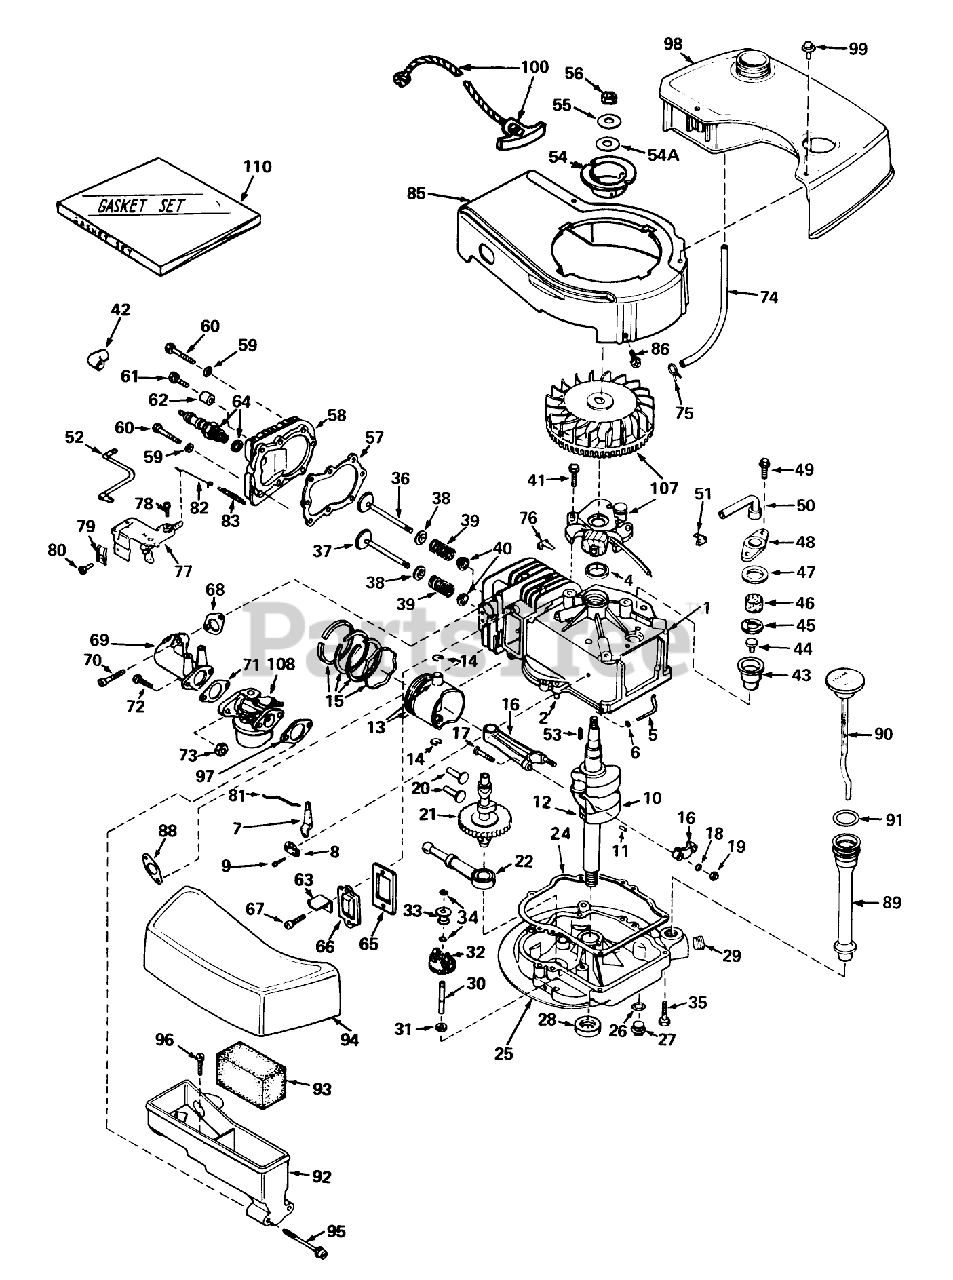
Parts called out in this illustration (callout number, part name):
1	Cylinder Assy. (Incl. Ref. #2, 4 105)
2	Pin-Dowel
4	OIL SEAL
5	Rod, Governor (Incl. No. 36)
6	Washer-Flat
7	Governor Lever
8	Clamp-Lever, Governor
9	Screw
10	Crankshaft Assembly (Incl. Nos. 12 13)
11	Pin, Groove
12	Gear, Crankshaft
13	Piston Pin Assembly (Incl. 2 of No. 14) (.010 Oversize)
13	Piston Pin Assembly (Incl. 2 of No. 14) (.020 Oversize)
14	Ring-Retaining, Piston Pin
15	Ring Set Piston (Std.)
15	Ring Set Piston (.010 Oversize)
15	Ring Set Piston (.020 Oversize)
16	Rod Assy., Connecting (Incl. Ref. #17)
17	Bolt, Connecting
18	Washer
19	LOCKNUT
20	Lifter-Valve
21	Camshaft (Mech. Compression Release)
22	Oil Pump ASM
24	Gasket, Mounting
25	Filter, Air Cleaner
26	Gasket-Oil Drain
27	Plug Oil Drain
28	Seal Oil
29	Plug Oil Drain
30	Shaft-Governor
31	Washer-Flat
32	Governor Gear ASM
33	Spool-Governor
34	Ring-Retaining
35	Screw (1/4-20 x 1-1/4)
36	Valve, Intake (Incl. Ref. #38, 39 40) (Std.)
36	Valve, Exhaust (1/32" Oversize) (Incl. Nos. 8, 9 10)
37	Valve, Exhaust (Standard) (Incl. Nos. 8, 9 10)
37	Valve, Exhaust (1/32" Oversize) (Incl. Nos. 8, 9 10)
38	Cap-Upper Valve Spring
39	Spring-Valve
40	Cap-Valve, Spring
41	Screw
42	Cover-Spark Plug
43	Body Breather Tube
44	Valve Check
45	2000A37 WIZARD ROTA
46	Element-Breather
47	Gasket-Breather
48	Cover Breather
49	Screw, Hex Hd. w/Conical
50	Tube, Breaker
51	Clip, Breather
52	Wire, Ground
53	Key Flywheel
54	Pulley Starter
54A	Washer Flat
55	Washer, Belleville
56	Nut, Flywheel
57	63573 GIL 42 SNWTHW
58	Head Cylinder
59	Washer
60	Screw
61	Screw Hex Hd. Cap
62	Space
63	Retainer Clip
64	Plug, Spark (J17LM or equiv.)
65	Gasket-Breather
66	Cover-Valve
67	Screw
68	Gasket, Intake
69	Pipe, Intake
70	Screw (1/4-20 x 1)
71	Gasket-Carburetor
73	Nut and Lock Washer (1/4-28)
74	Line-Fuel
75	Clamp-Line, Fuel
76	Clip-Wire
77	Control Assy., Speed
78	Screw (10-24 x 3/4)
79	Conduit
80	Screw (10-32 x 3/8)
81	Link Governor
82	Link Governor Spring
83	Spring Governor
85	53024/VAR.GT O/P W/
86	Screw
88	Gasket Exhaust
89	Tube, Oil Filler
90	Dipstick, OiI (Incl. No. 91)
91	O-Ring
92	Body Air Cleaner
93	Filer, Air
94	Cove, Air Cleaner
95	Screw Fil Hd.
96	Screw, Hex Hd.
97	Gasket-Air Cleaner
98	Tank Fuel
99	Screw (10-32 x 35/64)
100	Rope Assy., Starter
107	Magneto
108	Carburetor
110	53024/VAR.16HP O/P
